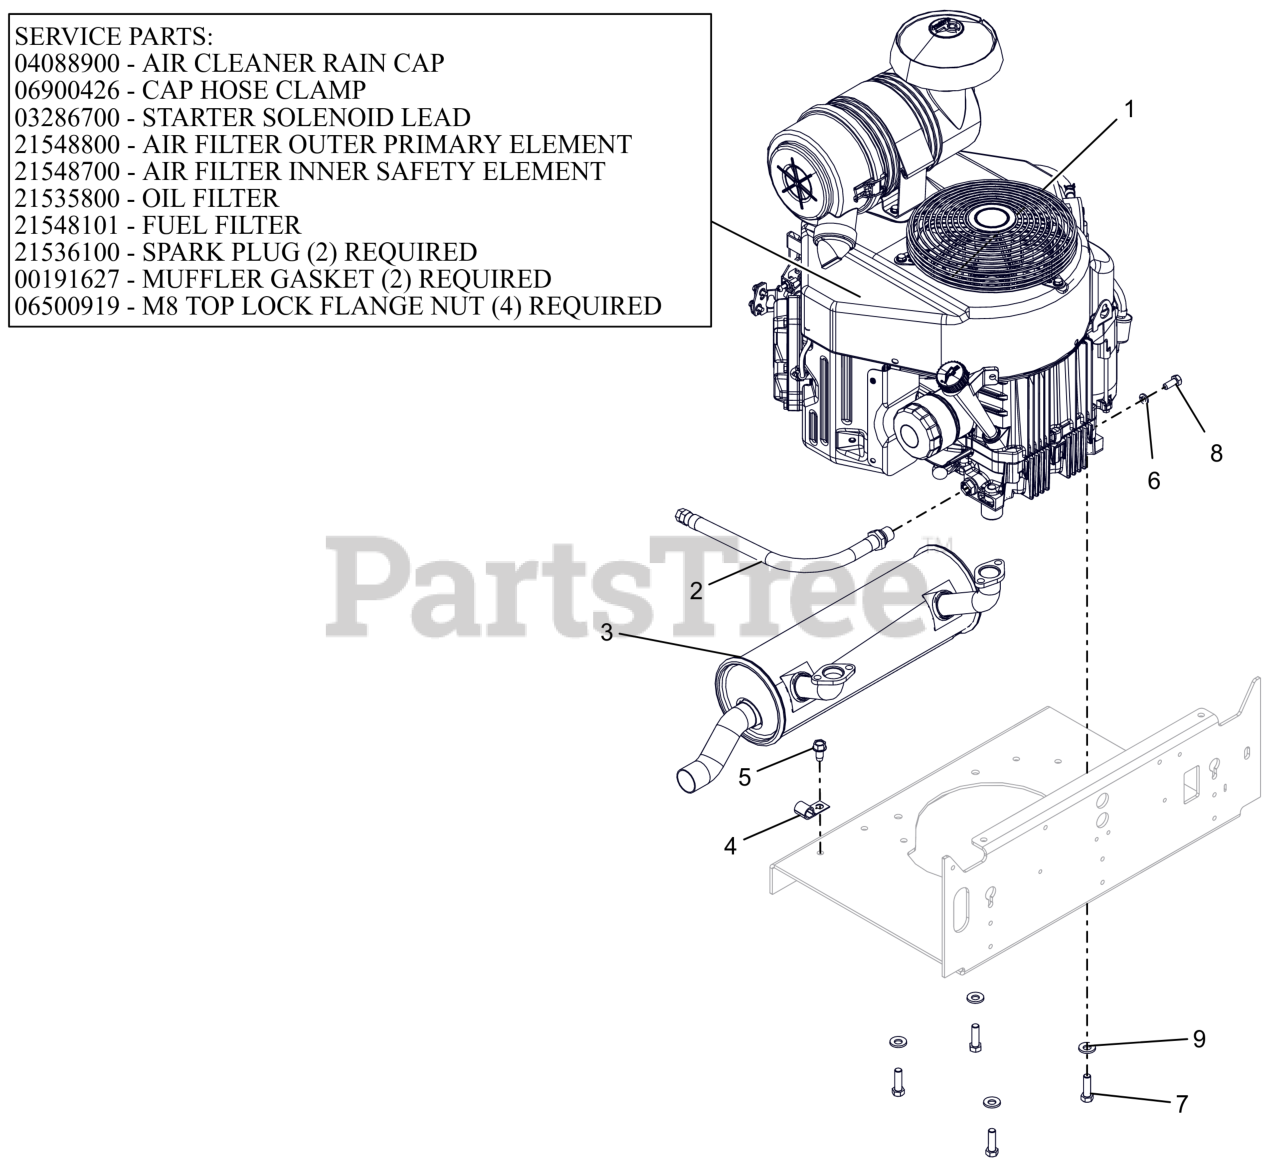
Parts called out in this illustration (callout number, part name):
1	ENGINE, KAWASAKI FX730
2	HOSE, OIL DRAIN
3	MUFFLER, KAW FX691/730
5	SCR,TAP .375-16X.75 HWH TR ZCC
6	WSHR,LK-REG .312X.078 ZCC
7	BLT, HEX .38-16X1.25 G5 ZCC NT
8	BLT, HEX M8-1.25X20 G8.8 ZCC
9	WASHER, 3/8" SPRING DISC
